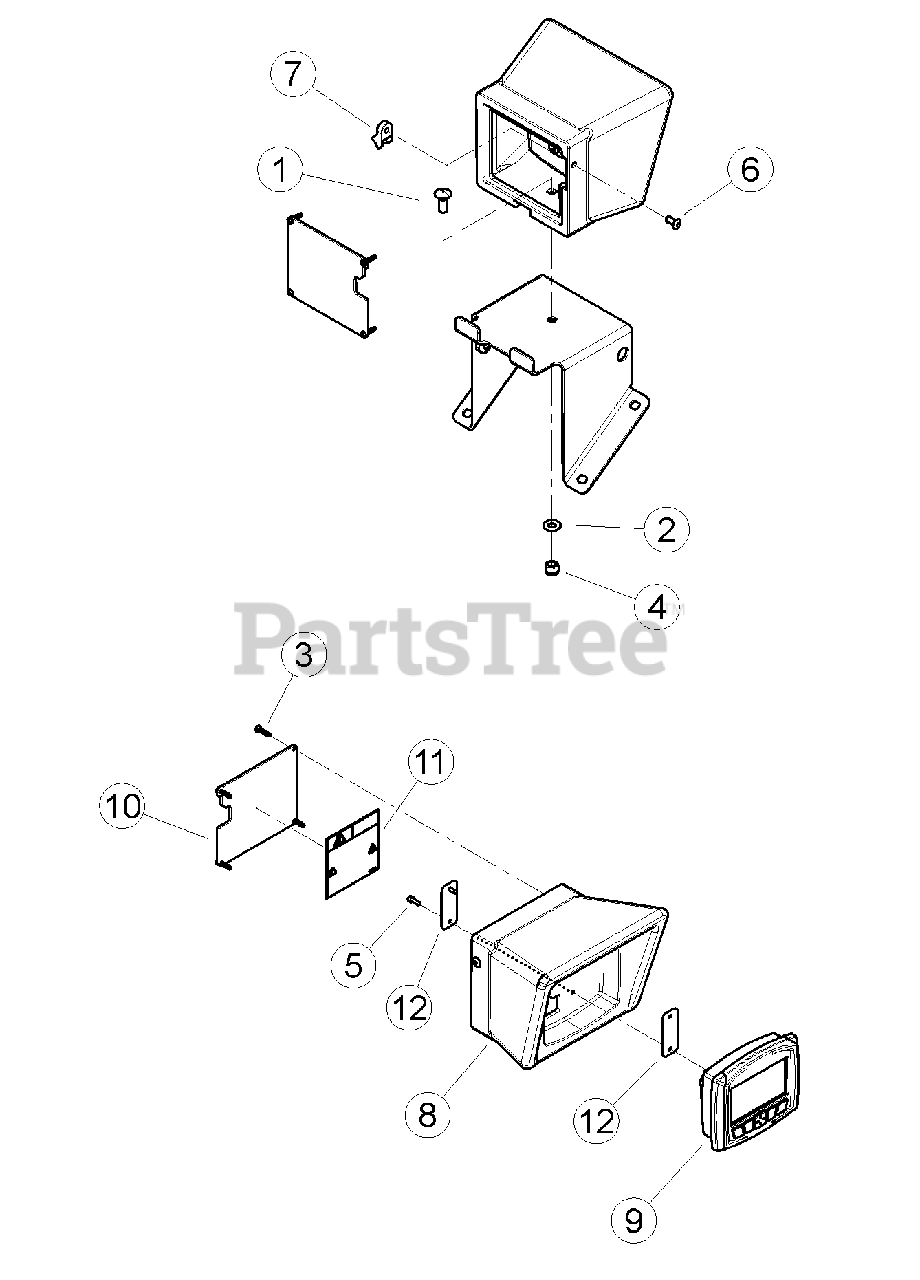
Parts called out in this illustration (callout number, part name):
1	BOLT, 3/8 X 1" GR5 CRG NC ZP
2	WASHER, 3/8" SAE FLAT ZP
3	SCREW, 10-16 3/4 LONG FOR PLASTIC
4	NUT, 3/8" NE NYLOCK ZP
5	SCREW, #8-32 X 1/2 SKT HD CAP
6	RIVET, AL BLIND 1/4 X 3/4 DOME HEAD
7	CLAMP, CABLE MOUNT
8	ENCLOSURE, CONTROLLER
9	CONTROLLER, CL-709-100 MASTER
10	ASSEMBLY, ENCLOSURE COVER WITH DECAL
11	DECAL, DDC MOUNTING INFO
12	PLATE, DDC WASHER
